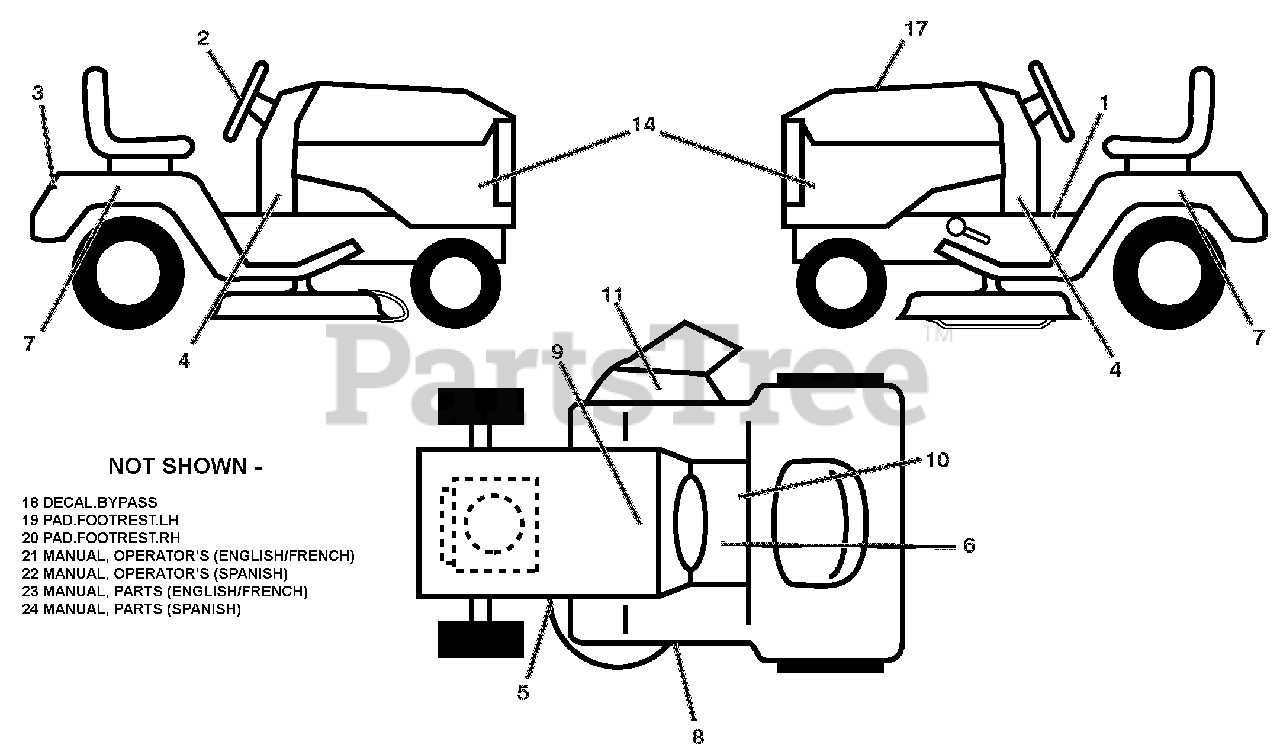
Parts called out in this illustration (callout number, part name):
1	DECAL, FENDER WARNING
2	DECAL.WHEEL.STEER.ARIENS
3	DECAL.FENDER.REAR.ARIENS
5	DECAL MOWER CAUTION
6	DECAL.WARNING SPARK
7	DECAL FENDER SIDE
8	DECAL.MOWER.SCH
9	DECAL.BAT.DAN/POI P/L SYM.WPN
10	DECAL.FENDER
11	DECAL DECK/DEFLECT. WARNING
14	DECAL.SDPNL.PWRDBY KOHL.ARIENS
17	DECAL REPLACEMENT
18	DECAL.BYPASS.FENDER
19	PAD FOOTREST LH TLT BLACK .428
20	PAD.FOOT PEDAL
21	OWNER'S MANUAL ENGLISH/FRENCH
22	OWNER'S MANUAL SPANISH
23	PARTS MANUAL ENGLISH/FRENCH
24	PARTS MANUAL SPANISH
